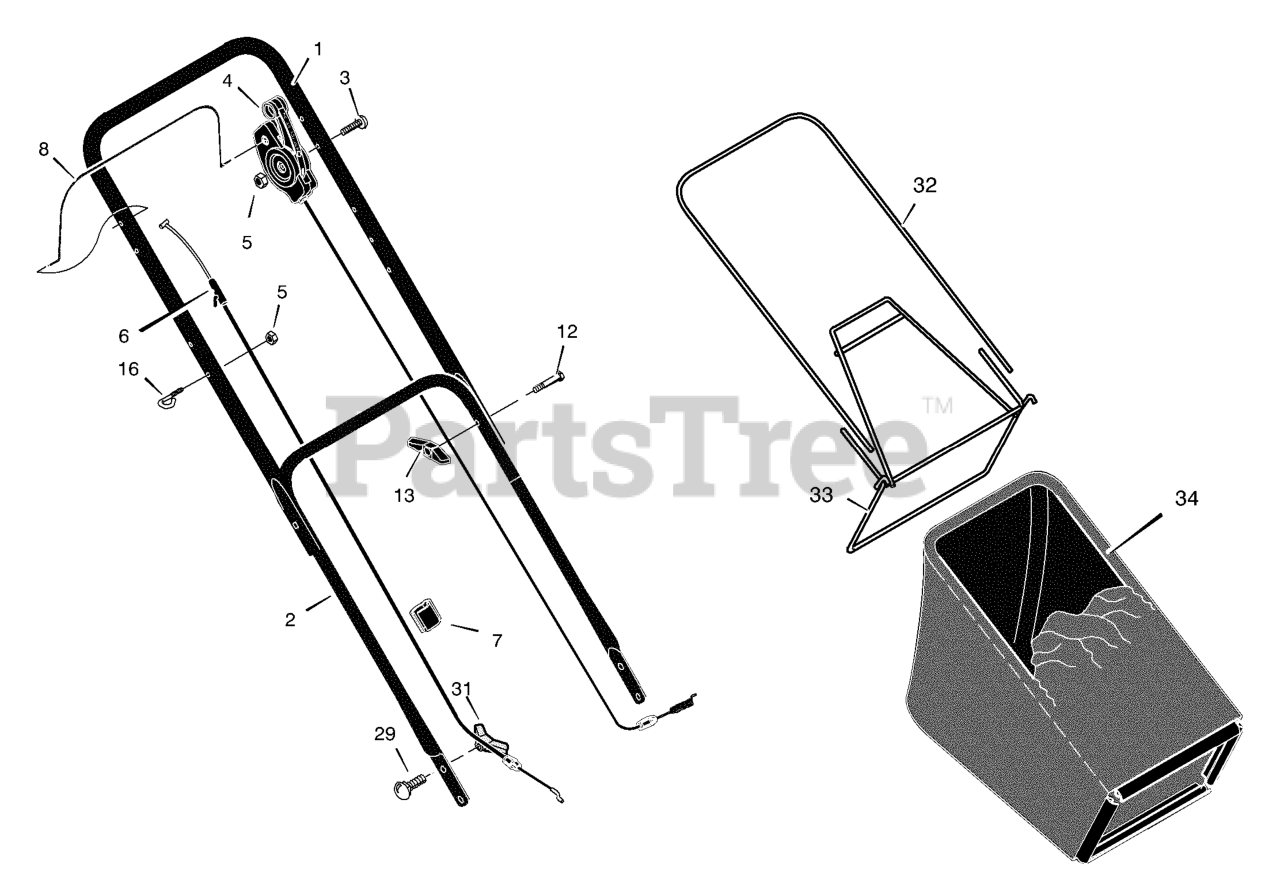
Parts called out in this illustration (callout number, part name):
1	Handle, Upper (Gray)
2	Handle, Lower (Gray)
4	Control, Drive
5	Locknut
6	Cable, Stop (Briggs)
7	Fastener, Double Cable
8	Lever, Stop
13	Knob
16	Guide, Rope
29	Bolt, Carriage
31	Knob, Plastic
32	Tube, Bag
33	Frame Assembly
34	Bag, Cloth
